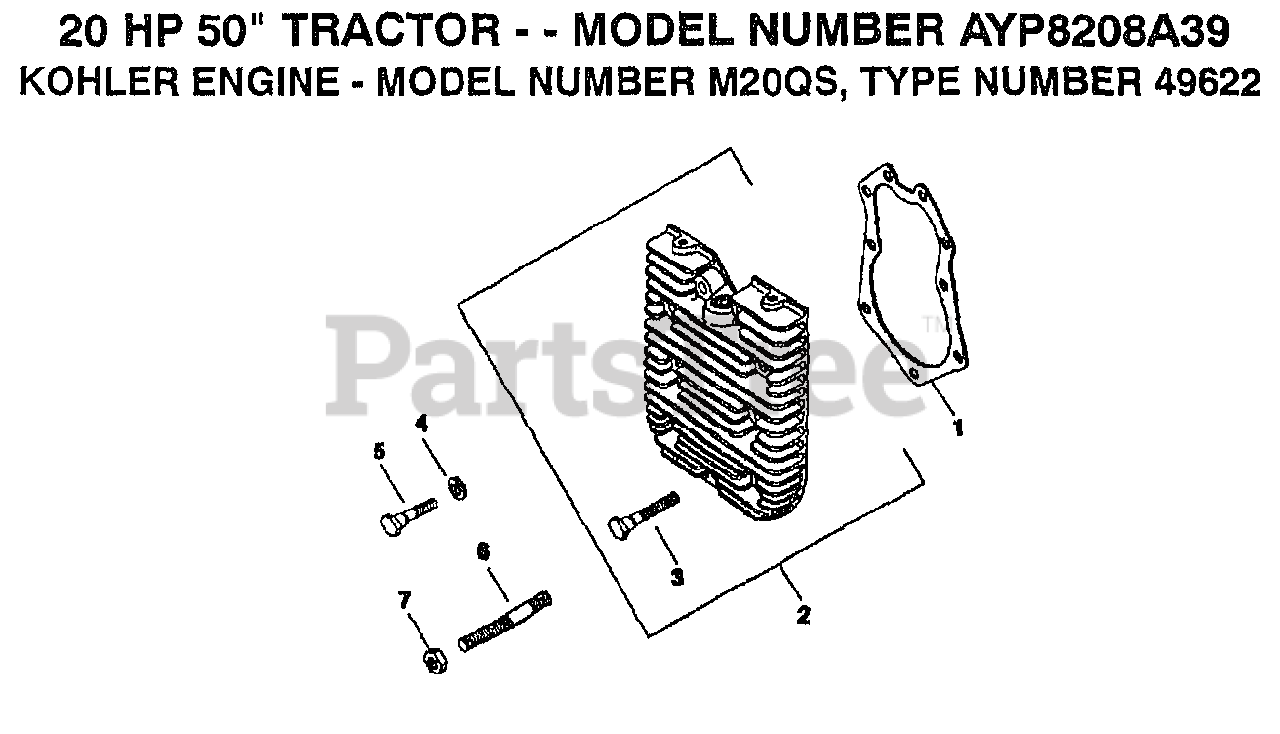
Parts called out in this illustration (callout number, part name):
1	GASKET, HEAD
2	KIT, CYLINDER HEAD
4	WASHER
7	NUT
